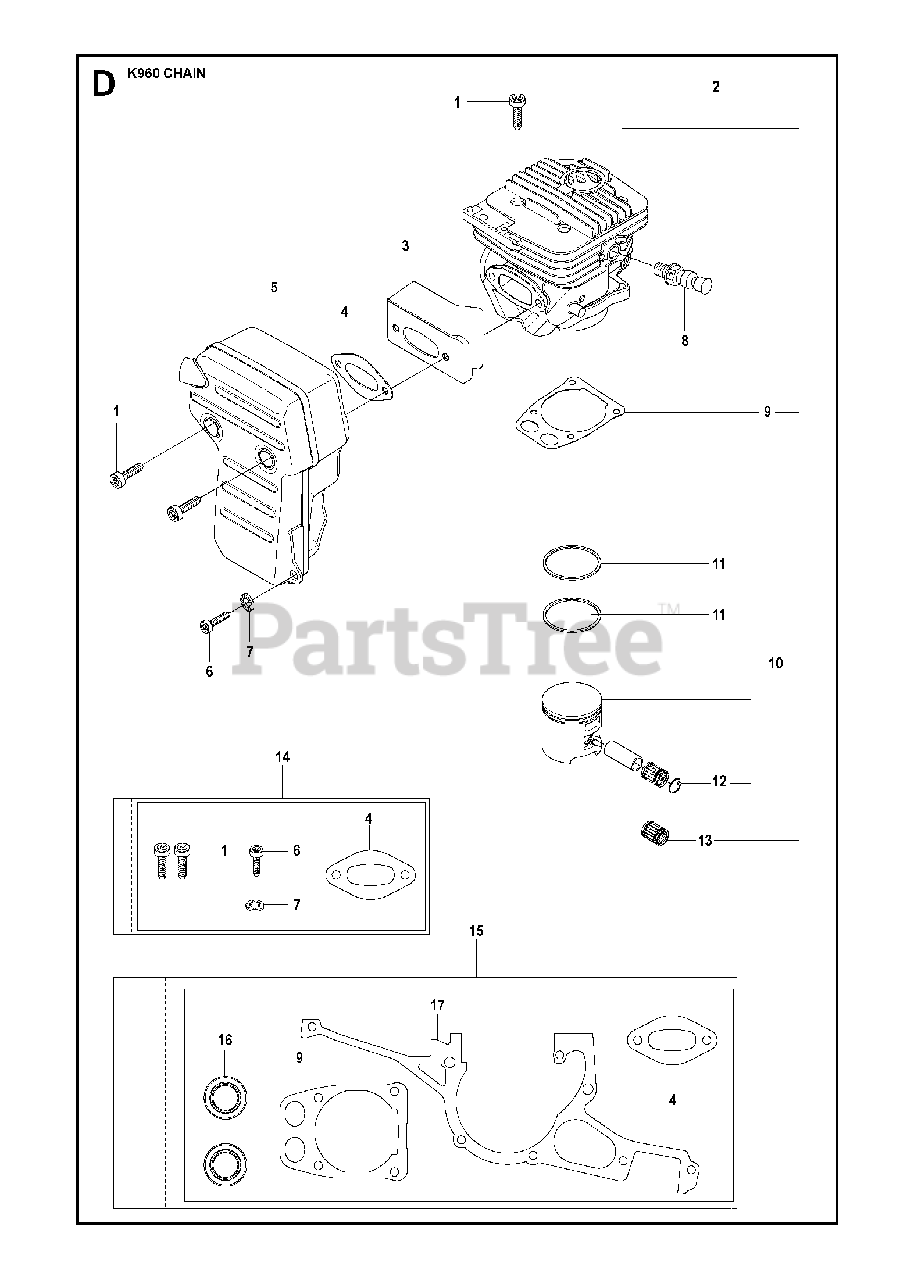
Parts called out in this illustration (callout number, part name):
1	SCREW ITXSCM
2	CYLINDER ASSYIncl. 9, 10, 13
3	HEAT DEFLECTOR
4	GASKET
5	MUFFLER ASSY
6	SCREW ITXSCM
8	DECOMPRESSION VALVE
9	GASKET
10	PISTONIncl. 11, 12
13	NEEDLE BEARING
14	GASKET KITIncl. 1, 4, 6, 7
15	GASKET KITIncl. 4, 9, 16, 17
16	SEALING RING
17	GASKET
